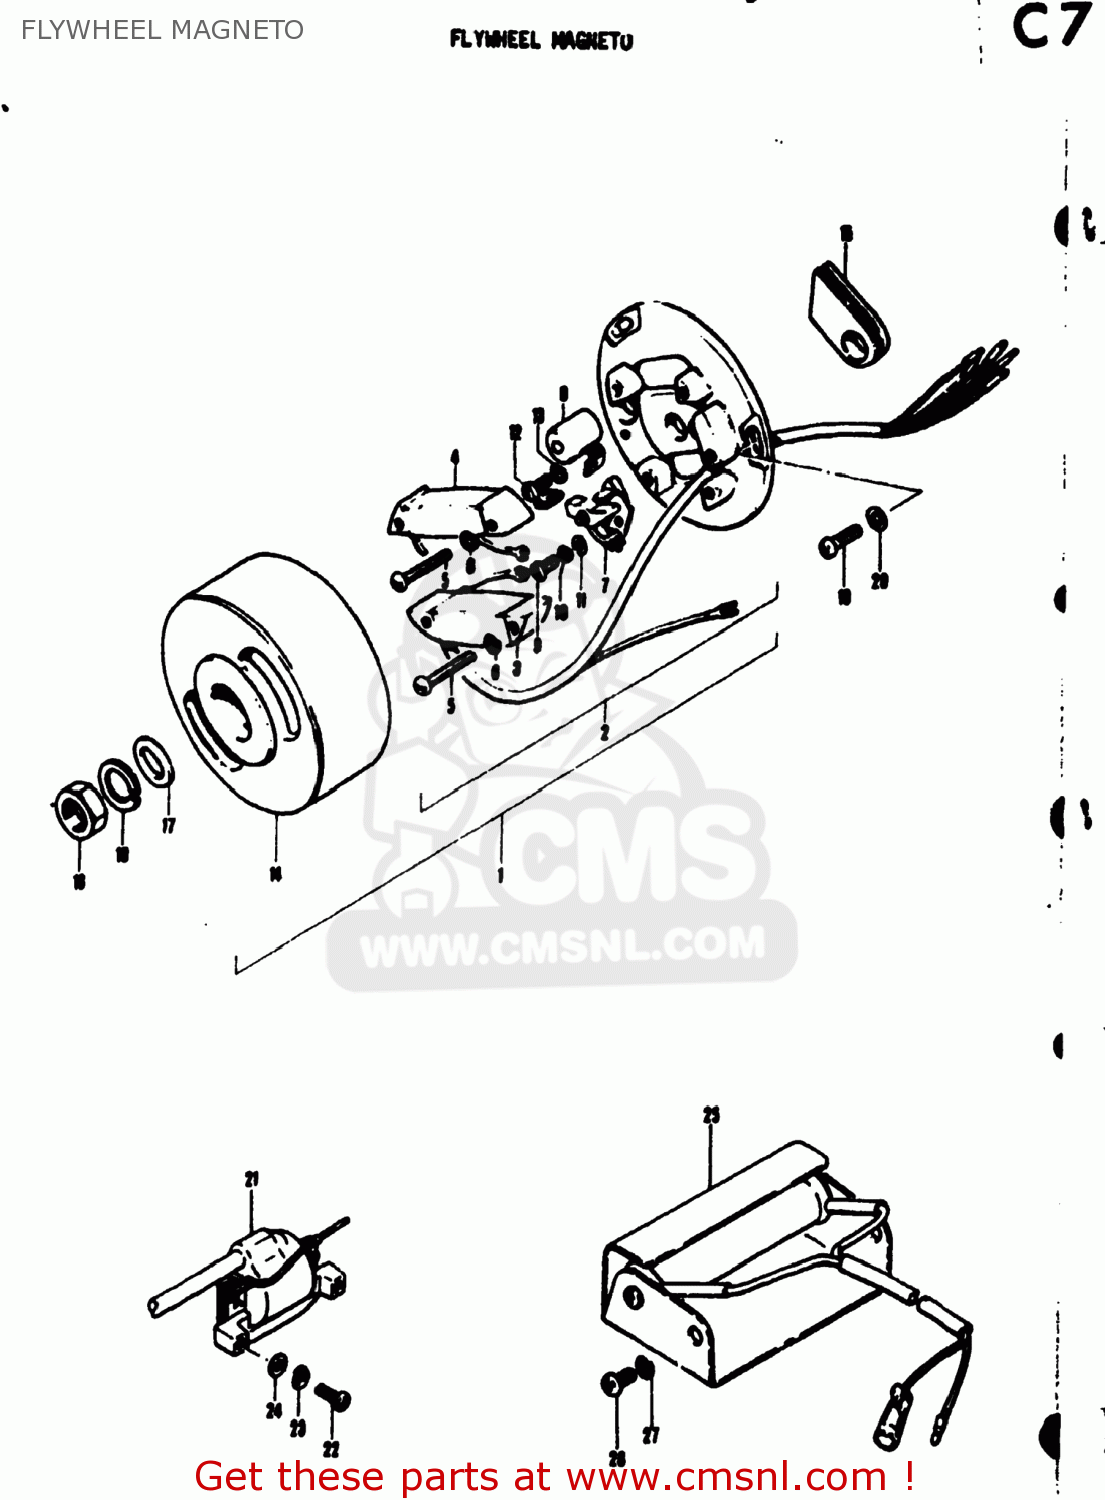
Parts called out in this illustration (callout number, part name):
1	MAGNETO ASSEMBLY
2	STATOR ASSEMBLY
3	COIL,LIGHTING
4	COIL
5	SCREW
6	LOCK WASHER
7	POINT ASSEMBLY,CONTACT
8	CONDENSER
9	.SCREW
10	LOCK WASHER
11	WASHER
12	.SCREW
13	LOCK WASHER
14	ROTOR ASSEMBLY
15	GROMMET
16	NUT
17	WASHER
18	LOCK WASHER
19	SCREW
20	WASHER
21	COIL ASSEMBLY,IGNITION
22	Screw
23	LOCK WASHER
24	WASHER
25	MAGNETO RESISTOR ASS
26	SCREW
27	LOCK WASHER
